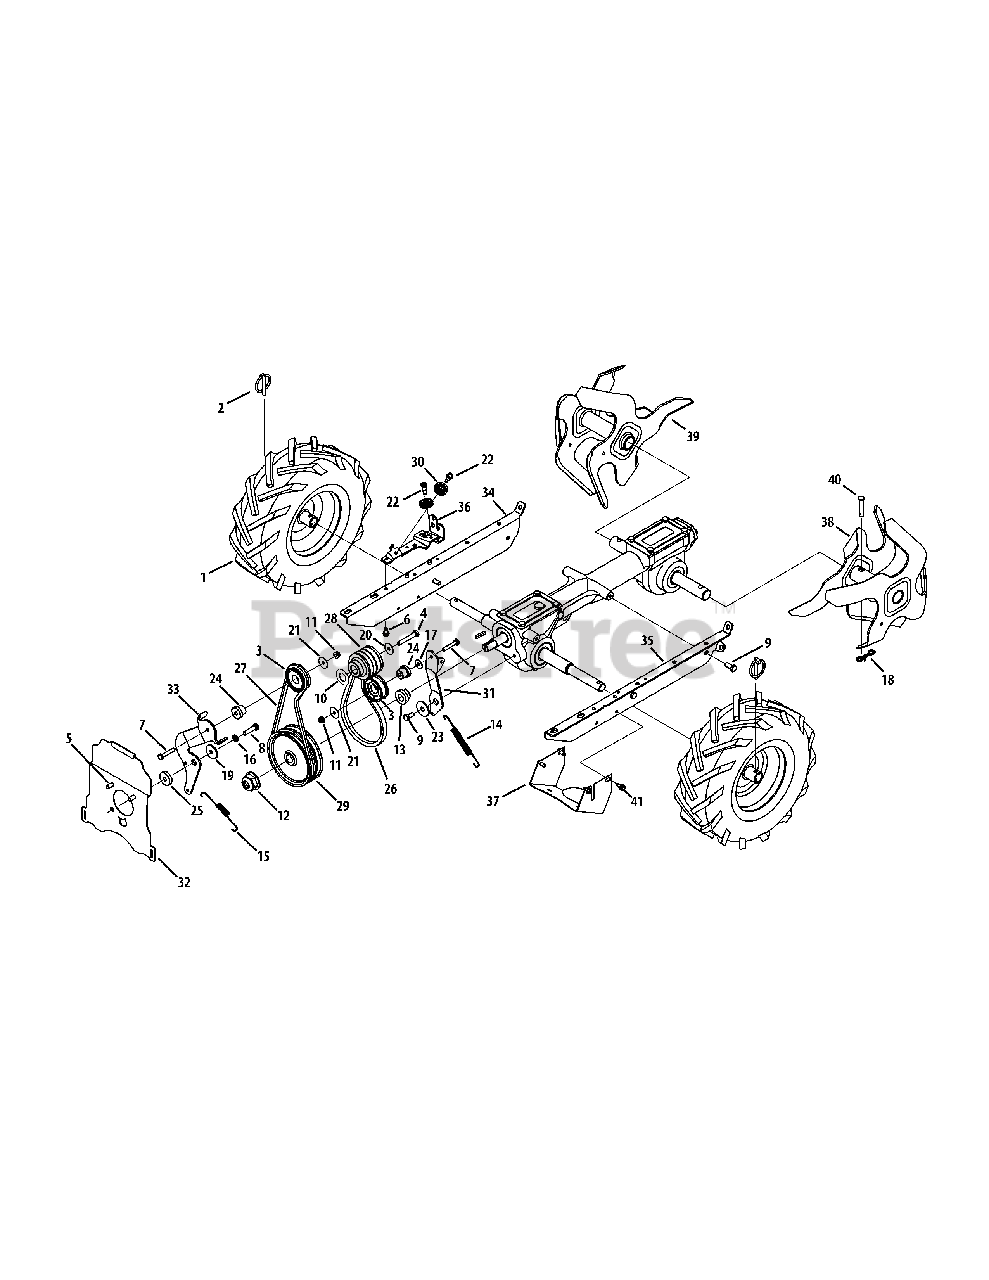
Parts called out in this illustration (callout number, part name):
1	Complete Whl. Ass., 13 x 5 x 6
1	Rim, 6.0 X 3.25
1	Tire, 13 x 5 x 6
3	Idler Pulley Assembly
4	Hex Head Screw, 3/8-24 x 2.00
5	Hex Head Screw, 5/16-24 x .625
6	Self Tapping Screw, 1/4-20 x .500
7	Hex Head Screw, 1/4-20 x 1.50
8	Hex Head Screw, 5/16-18 x 1.25
9	Hex Head Screw, 5/16-18 x .75, Patch
10	Washer, Flat, .760 x 1.50 x .120
11	Nylon Hex Lock Nut, 1/4-20
12	Nut, 9/16-18, Flange Lock
13	Hub, 5/8 Spline
14	Extension Spring, .480 OD X 5.00 LG
15	Extension Spring, LT5 PTO
16	Lock Washer, 5/16
17	Washer, .28 x .74 x .063
18	Cotter Pin, Bow Tie
19	Flat Washer, .330 X 1.25 X .120
20	Bell Washer, .396 x 1.140 x .095
21	Flat Washer, .265 x 1.0 x .030
22	Shoulder Screw, .342 x .335 1/4-28
23	Pivot Idler Spacer
24	Shoulder Spacer, .260 x .785 x .538
25	Pivot Idler Spacer
26	V-Belt, 4L x 25.375 Long
27	V-Belt, 3L x 29.125 Long
28	Engine Pulley
29	Transmission Pulley
30	Cable Roller
31	Idler Bracket, Forward
33	Idler Bracket, Reverse
34	Mounting Frame, RH
35	Mounting Frame, LH
36	Pulley Bracket
37	Pulley Shield
38	Tine Assembly, LH
39	Tine Assembly, RH
40	Clevis Pin, .375 x 1.75
41	Self Tapping Screw, 1/4-14 x .625
